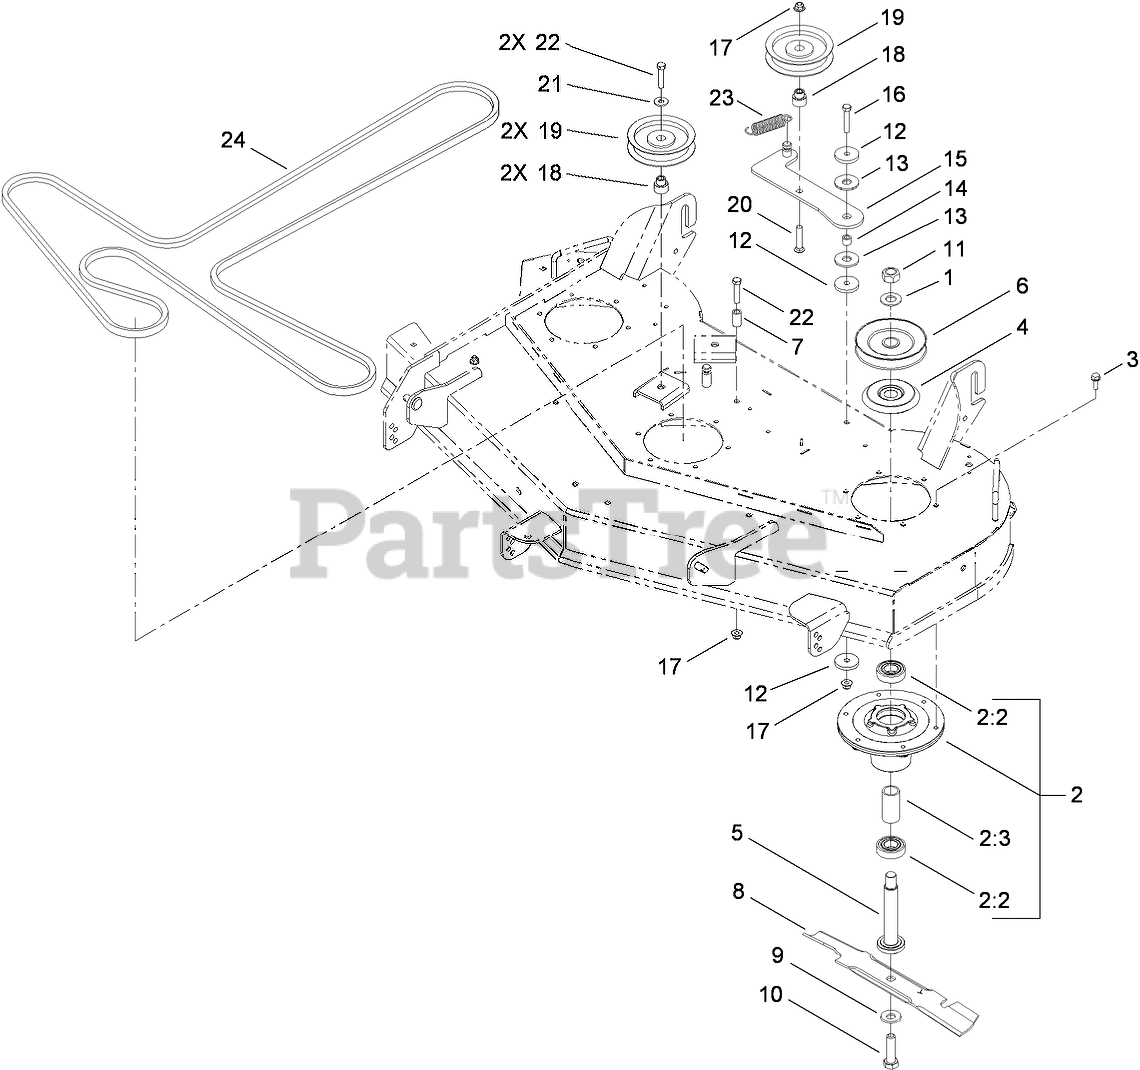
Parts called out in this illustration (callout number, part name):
1	WASHER
2	SPINDLE ASM
2:2	BEARING-BALL
2:3	SPACER-BEARING
3	SCREW-TAPTITE
4	SHIELD-BEARING
5	SHAFT-SPINDLE
6	PULLEY
7	SPACER
8	BLADE-MULCH, 16.50 INCH
9	WASHER-BELLEVILLE
10	SCREW-BLADE
11	NUT-HEX
12	WASHER-PLAIN
13	WASHER-FRICTION, COMPOSITE
14	BUSHING-LEVER, LIFT
15	ARM-IDLER
16	SCREW-HH
17	NUT-HF, NI
18	BUSHING-IDLER
19	PULLEY-IDLER
20	SCREW-CARR
21	WASHER-HARDENED
22	SCREW-HH
23	SPRING-EXTENSION
24	V-BELT
